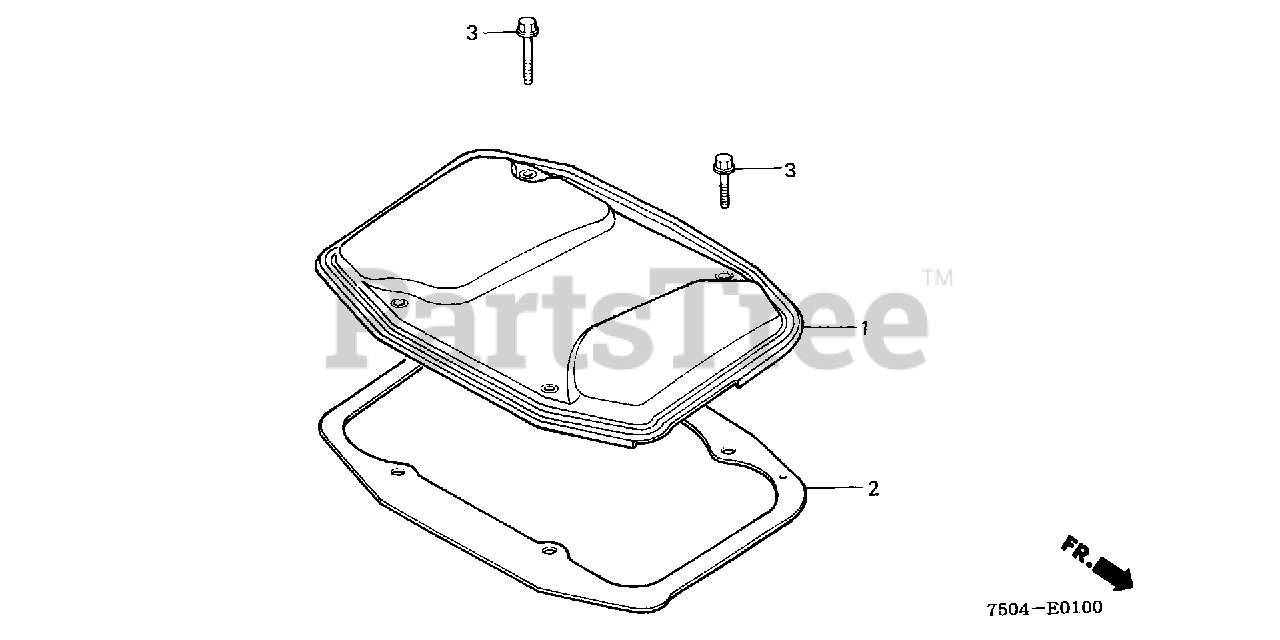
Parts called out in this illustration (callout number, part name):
1	COVER, CYLINDER HEAD
2	GASKET, CYLINDER HEAD COVER
3	BOLT, FLANGE (6X20)
